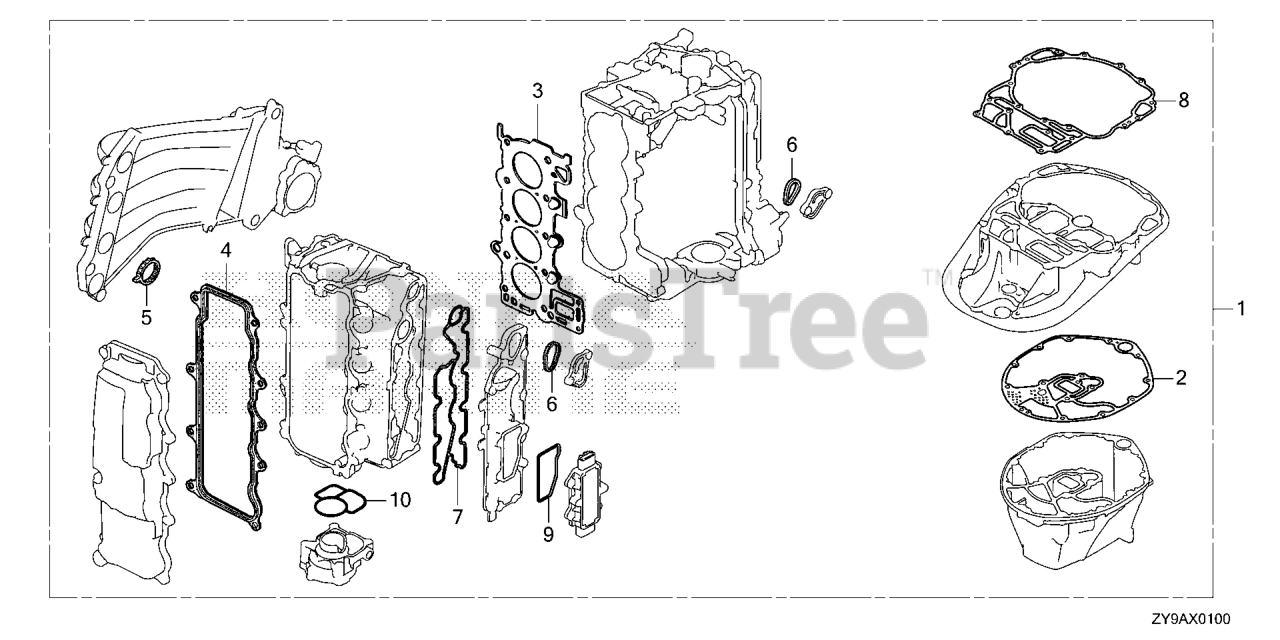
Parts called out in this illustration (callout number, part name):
1	GASKET KIT
2	GASKET, OIL PAN
3	GASKET, CYLINDER HEAD
4	GASKET, HEAD COVER
5	GASKET, IN. MANIFOLD
6	O-RING, THERMOSTAT COVER
7	GASKET, EX. WATER JACKET COVER
8	GASKET, MOUNT CASE
9	GASKET, REGULATOR
10	O-RING, OIL PUMP
